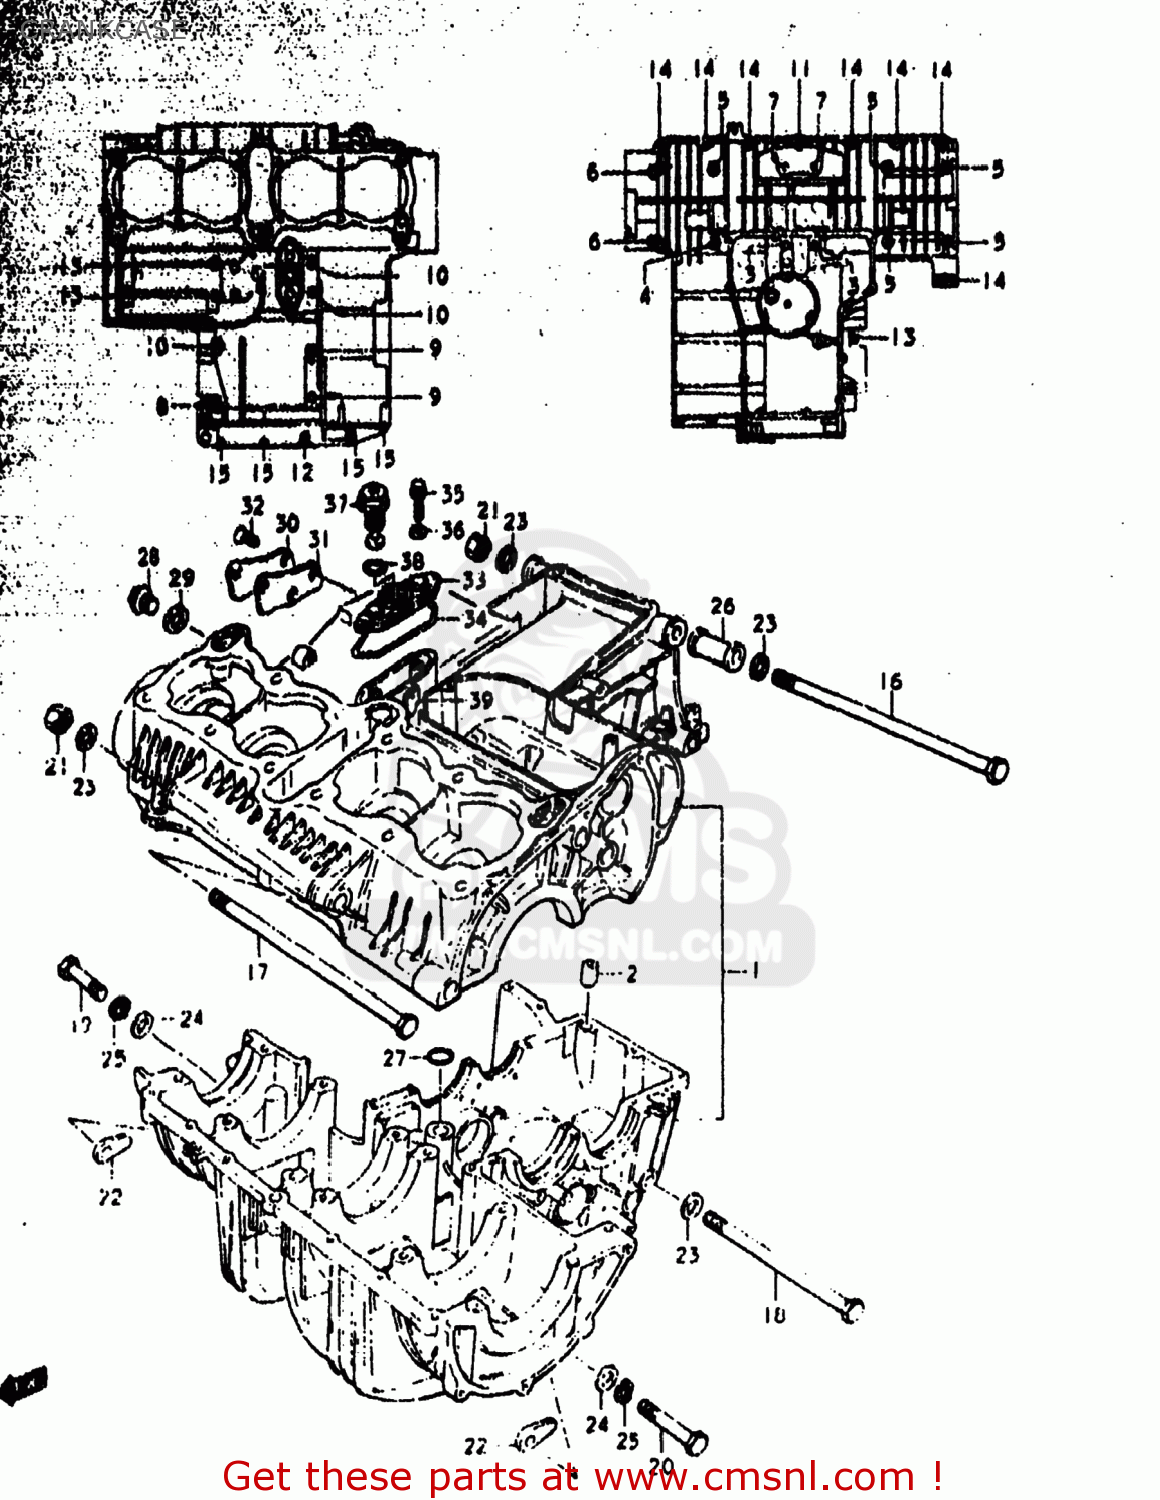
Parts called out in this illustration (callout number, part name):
1	CRANKCASE SET
2	PIN
3	BOLT
4	BOLT
5	BOLT 8X90
6	BOLT 8X65
7	BOLT
8	BOLT
9	BOLT
10	BOLT (6X75)
11	BOLT ,6X50
12	BOLT,UNDER
13	BOLT
14	BOLT 6X35
15	BOLT
16	BOLT 10X265
17	BOLT 10X250
18	BOLT(10X165)
19	BOLT 10X60
20	BOLT (10X50)
21	NUT
22	NUT
23	WASHER
24	WASHER(10.5X20X3.2)
25	LOCK WASHER
26	SPACER,ENGINE MOUNT
27	O RING(D:3.2,ID:12.9)
28	PLUG (14X12)
29	GASKET(14X19.2X2) (NAS)
30	CAP,OIL GALLERY
31	GASKET,OIL GALLERY (MCA)
32	SCREW
33	HOUSING,OIL PRESSURE SWITCH
34	O RING,PRESSURE SWITCH HOUSING
35	BOLT
36	GASKET (NAS)
37	SWITCH ASSEMBLY
38	O RING(D:1.9,ID:18.8)
39	GROMMET,STARTING MOTOR
